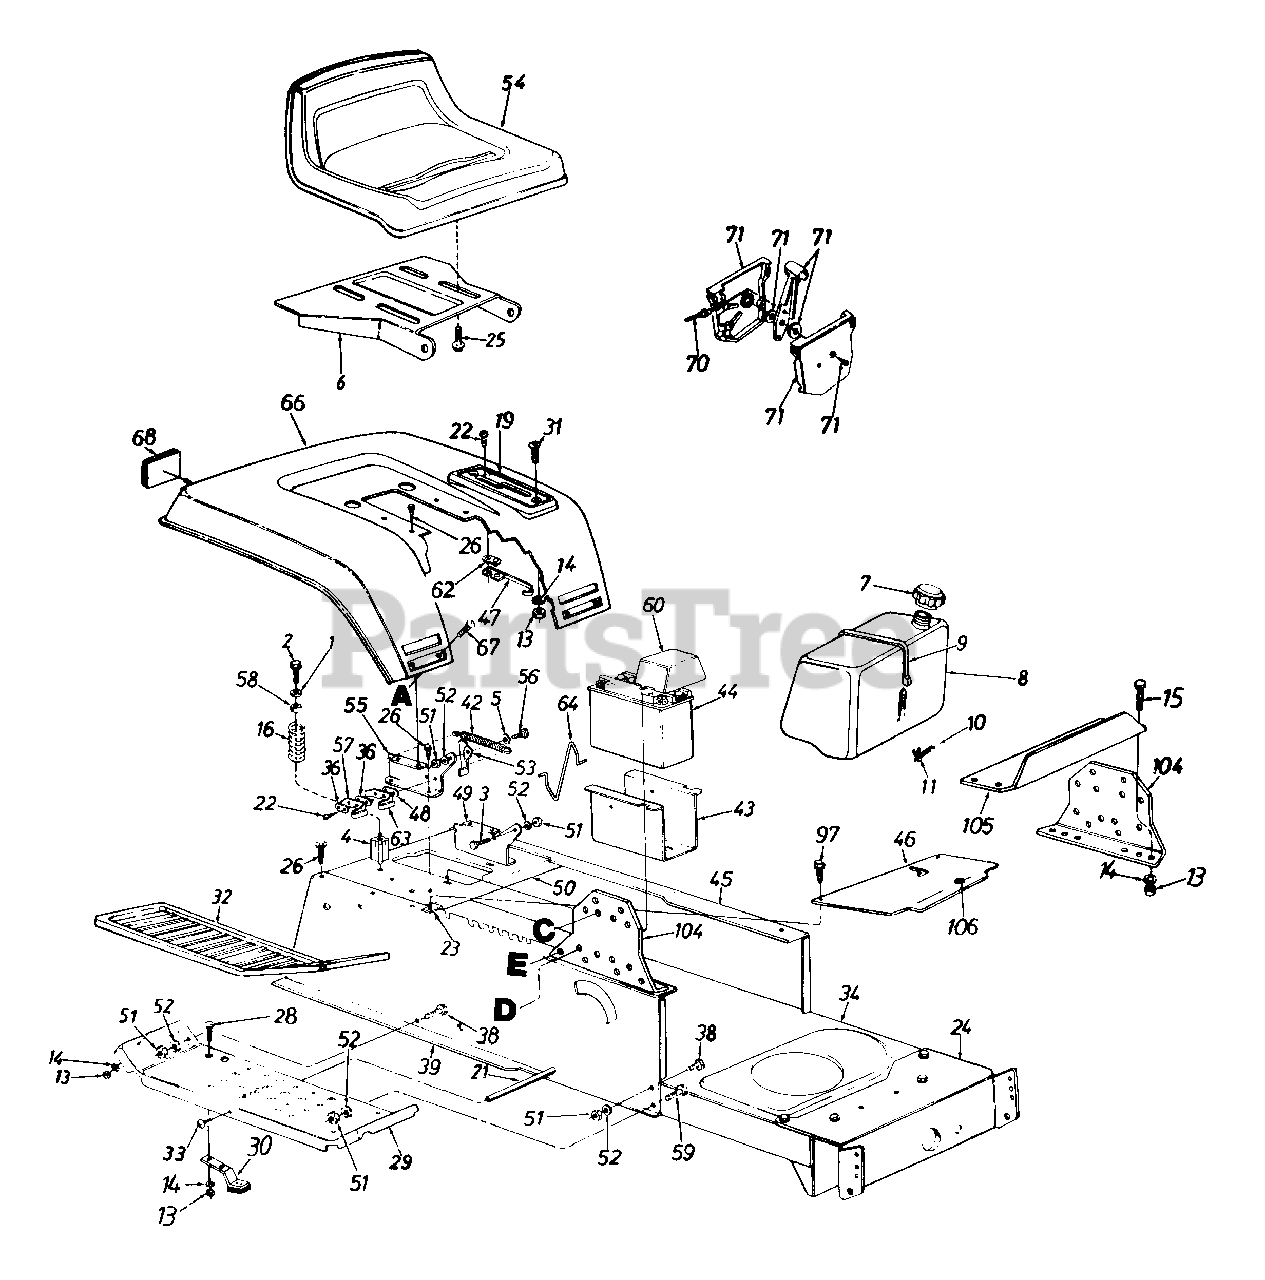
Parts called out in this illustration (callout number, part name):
1	Fl-Wash..344" I.D. x .875"
2	Hex Wash. Hd. Tap Scr. 5/16-18 x 3.25" Lg.
3	Shld. Bolt .437" Dia. x .162"
4	Spring Spacer
5	Spr-Wash..445" I.D. x .75
6	Seat Pivot Bracket
7	Fuel Cap w/o Gasket
8	Fuel Tank
9	Tie Strap
10	Fuel Line 15" Lg.
11	Hose Clamp
13	Hex Nut 1/4-20 Thd.
14	L-Wash. 1 4" I.D.
15	Hex Bolt 1/4-20 x .62" Lg.
16	Compression Spring
19	Speed Control Index Brkt.
21	Running Board Rod
22	Hex Wash. Hd. AB-Tap Scr. #8 x .50" Lg.
23	Speed Nut #102
24	Front Pivot Brkt.
25	Hex Tap Scr. 3/8-16 x .75"
26	Hex Wash. Hd. AB-Tap Scr. 5/16 x .75" Lg.
28	Carriage Bolt 1/4-20 x .62"
29	Running Board (R.H. & L.H.)
30	Blade Brake Ass'y.
31	Truss Mach. Scr. 1/4-20 x .75" Lg.
32	Rubber Foot Pad - L.H.
33	Pan Hd. Cutting Scr. 5/16-18 x .75" Lg.
34	Lower Frame
36	Insulator Plate
38	Hex Bolt 5/16-18 x .75" Lg.
39	Upper Frame - R.H.
42	Extension Spring 5.31" Lg.
43	Battery Tray
44	12-V Battery (275 Cold Crank Amps)
45	Upper Frame - L.H.
46	Shift Cover
47	Reverse Safety Switch
48	Insulator Boss Plate
52	L-Wash. 5/16" I.D.
53	Seat Lift Brkt.
54	Seat - 8-7 8" High
56	Shld. Bolt .437" Dia. x .268"
57	Spring Switch
58	Bushing
59	Hex Wash. Hd. Scr. 5/16-18 x .87" Lg.
60	Battery Cover
62	Insulator Nut Plate
63	Safety Switch (Seat)
64	Battery Tray Clip
68	Reflector
70	Throttle Wire
71	Throttle Control Box Ass'y.
97	Truss Mach. B-Tap Scr. #10 x .5" Lg.
